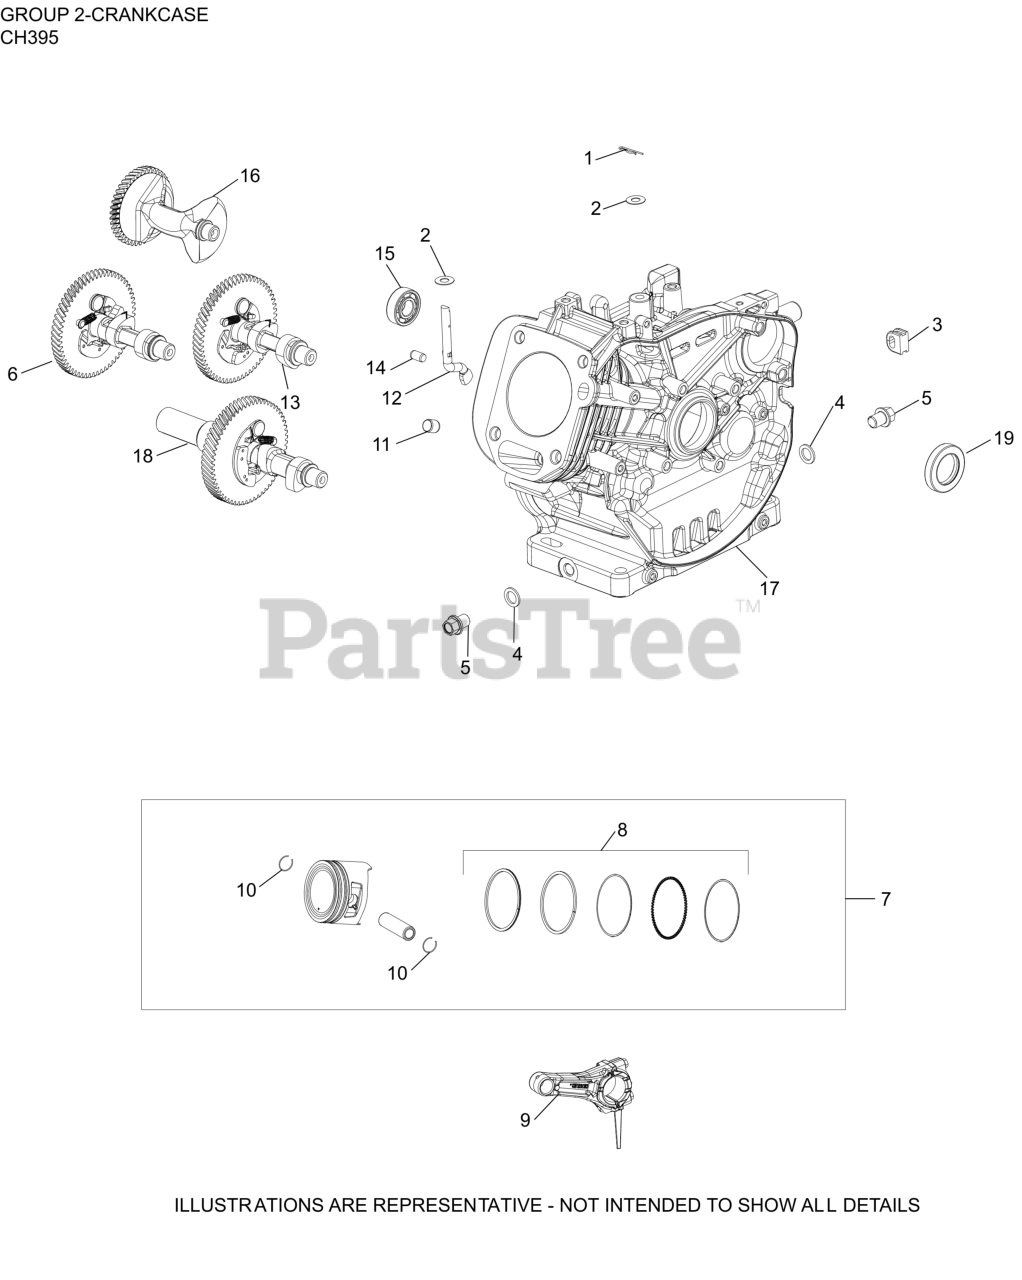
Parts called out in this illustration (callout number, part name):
1	CLIP, GOVERNOR SHAFT
2	WASHER, FLAT
3	GROMMET, CRANKCASE
4	WASHER, DRAIN PLUG
5	KIT, DRAIN PLUG
7	KIT, PISTON AND RINGS
8	RING SET- USE 17 874 06-S
8	RING, SET PISTION (std)
9	ROD, CONNECTING ASSEMBLY
10	RETAINER, PISTON PIN
11	PIN, DOWEL CYLINDER HEAD
12	SHAFT, GOVERNOR CROSS
13	CAMSHAFT ASSEMBLY
14	PIN, DOWEL
16	SHAFT, BALANCE
17	CRANKCASE
19	SEAL, RADIAL SHAFT
